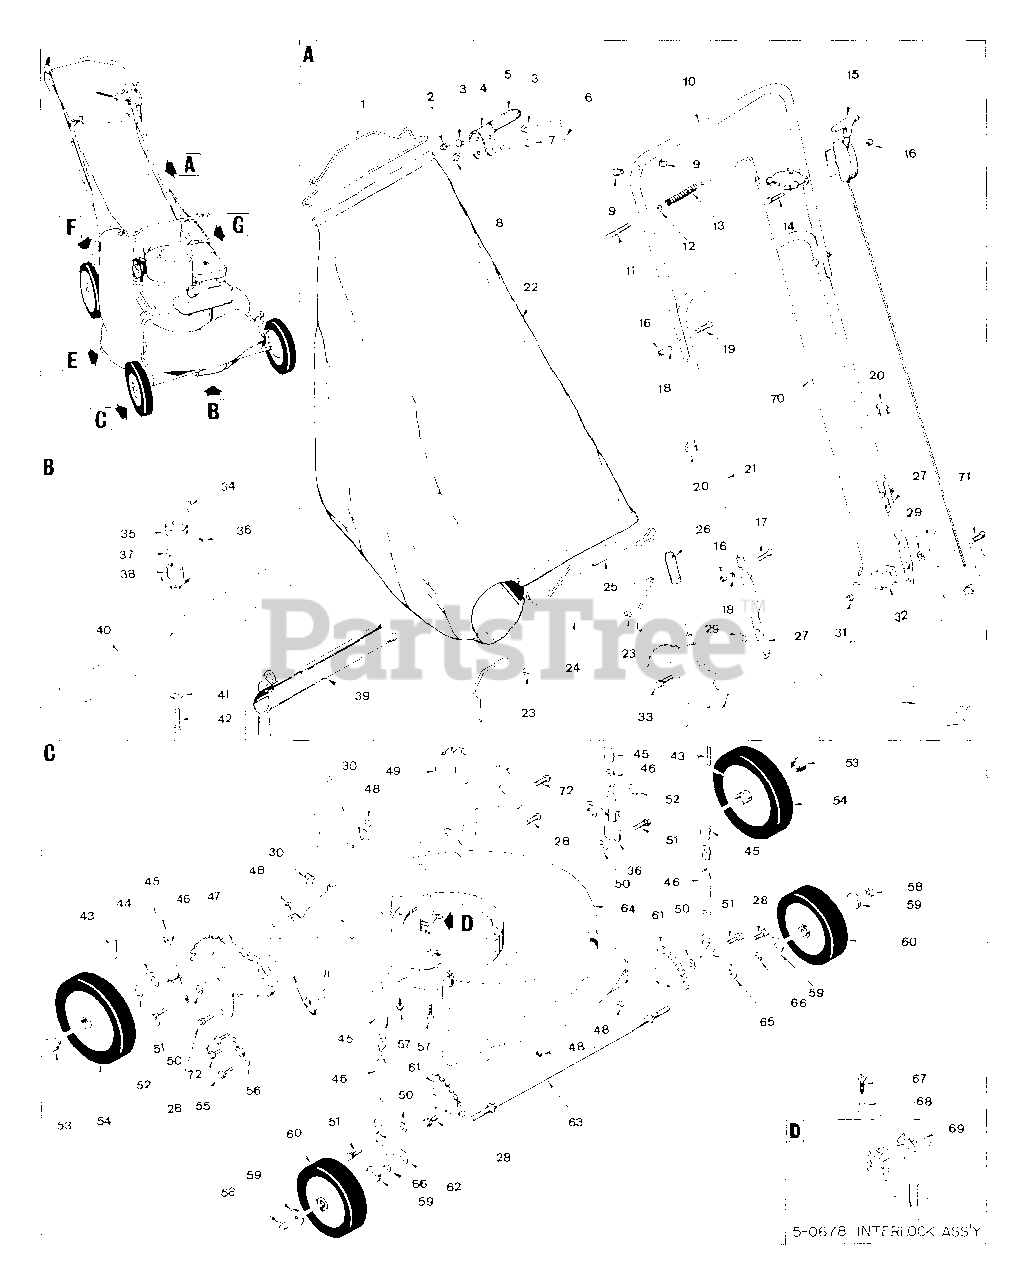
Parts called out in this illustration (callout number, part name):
1	Rear Wire
2	Push Nut
3	Bushing
4	Clutch Handle
5	Grip
6	Clutch Pull Rod
7	Pin
8	Push Nut
9	Bushing
10	Upper Str. Handle
11	Grip
12	5/16" Washer
13	Spring
14	1/4-28 x 2" H.H.C.S.
15	Throttle Control, B.& S.
15	Throttle Control, Tecumseh
16	1/4 28 Hex Nut
17	1/4-28 x 1 1/2" H.H.C.S., Gr. 5
18	1/4 Internal Tooth Lock Washer
19	1/4-28 x 1 1/4" H.H.C.S., Gr. 5
21	Lower Handle Pivoting
22	Grass Bag
23	Nylon Ring
24	Roll Bar
25	Front Wire
26	Vinyl Cover
27	Lower Handle
28	5/16 x 18 x 5/8 HWS ST.
29	5/16 Int.-Ext. Tooth Lock Washer
30	T-Nut
31	5/16-24 Lock Nut
32	ANCHOR, Speed Control
33	5/16-24 x 1 1/4" H.H.C S.
34	Hi - Pro - Key
35	Engine Pulley
36	Rear Wheel Arm Assembly, L.H
37	KEY, (#6) 5/32 x 5/8" Woodruff
38	Blade Drive Hub
39	Slider Assembly
40	Blade
41	Cone Washer
42	3/8-24 x 1-1/2" Gr 5 Cap Screw
43	Roll Pin
44	Rear Wheel Arm Assembly, R.H.
45	Grip
46	Height Latch
47	Rear Bracket, R.H.
48	5/16-18 Jam Nut
49	Rear Bracket, L.H.
50	Bolt Retainer
51	5/16-16 Shoulder Screw
52	3/4" Washer
53	Rear Hub Cap
54	Rear Wheel
55	1/4-20 x 3/8" H.W.S.T.
56	Holder Half
57	3/8-18 x 1" H.W.S. ST. Engine Bolt
58	7/16-20 Jam Lock Nut
59	Front Hub Cap
60	Front Wheel, 7 x 1.50
61	Front Bracket
62	Wheel Arm, Front R.H
63	Front Axle
64	Deck
65	Wheel Arm, Front L.H
66	Spring Washer
67	8-C x 3/4 SMS.
68	No. 8 Tab Washer
69	Interlock Assembly
70	Speed Control Lever
71	5/16-24 x 1" H.H.C.S.
72	5/16-18 x 3/4" H.W.S. ST.
